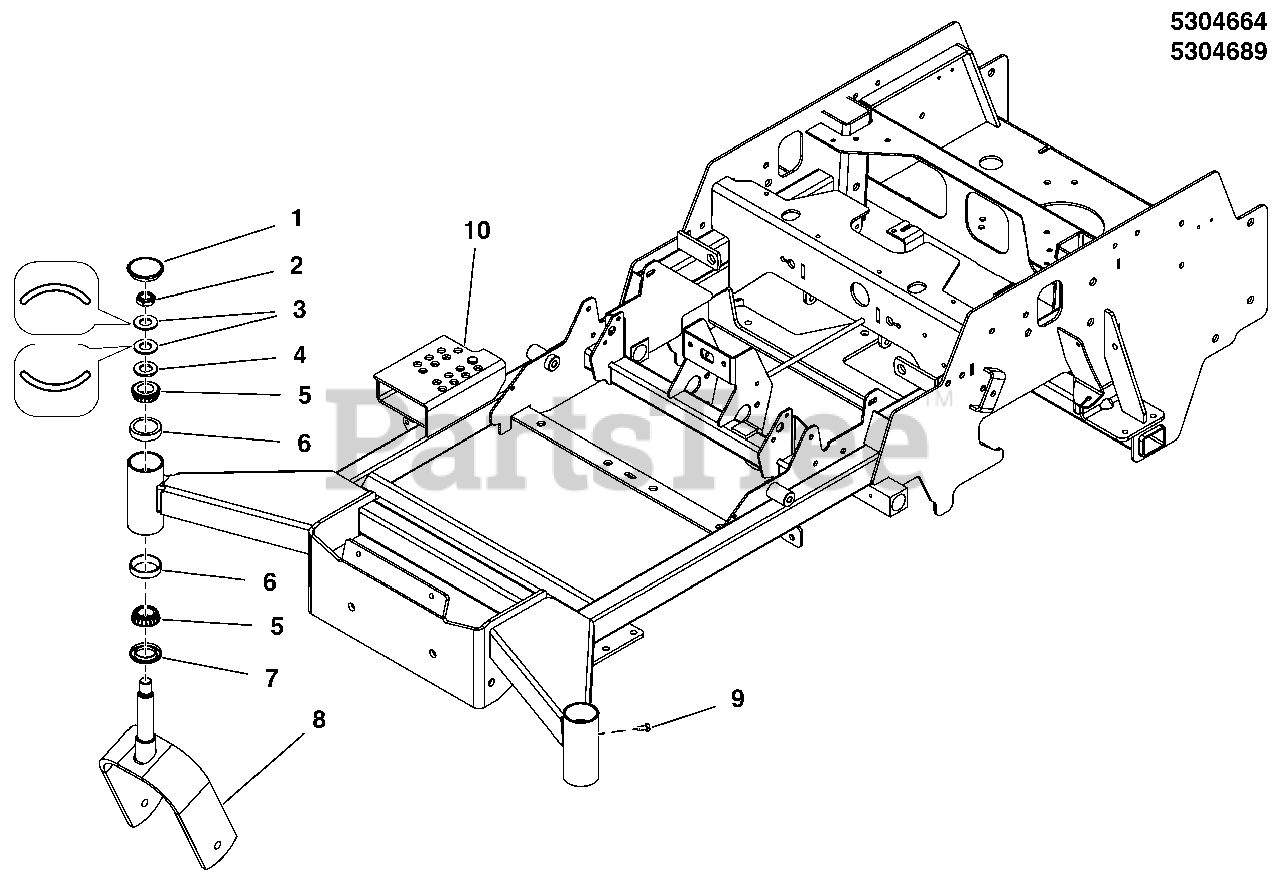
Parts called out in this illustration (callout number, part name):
1	CAP, GREASE, LOW PROFILE
2	NUT, 3/4-16, HEX JAM NYLON LOCK
3	WASHER, BELLEVILLE - 1.500 X .755
4	WASHER, 3/4 SAE
5	BEARING, TAPERED ROLLER, 1
6	BEARING CUP
7	SEAL, GREASE
8	WELD, CASTER YOKE - RED
9	BOLT, 1/4-28 X 1/2, GD5 CZ
10	* WELD, MAIN FRAME - RED
